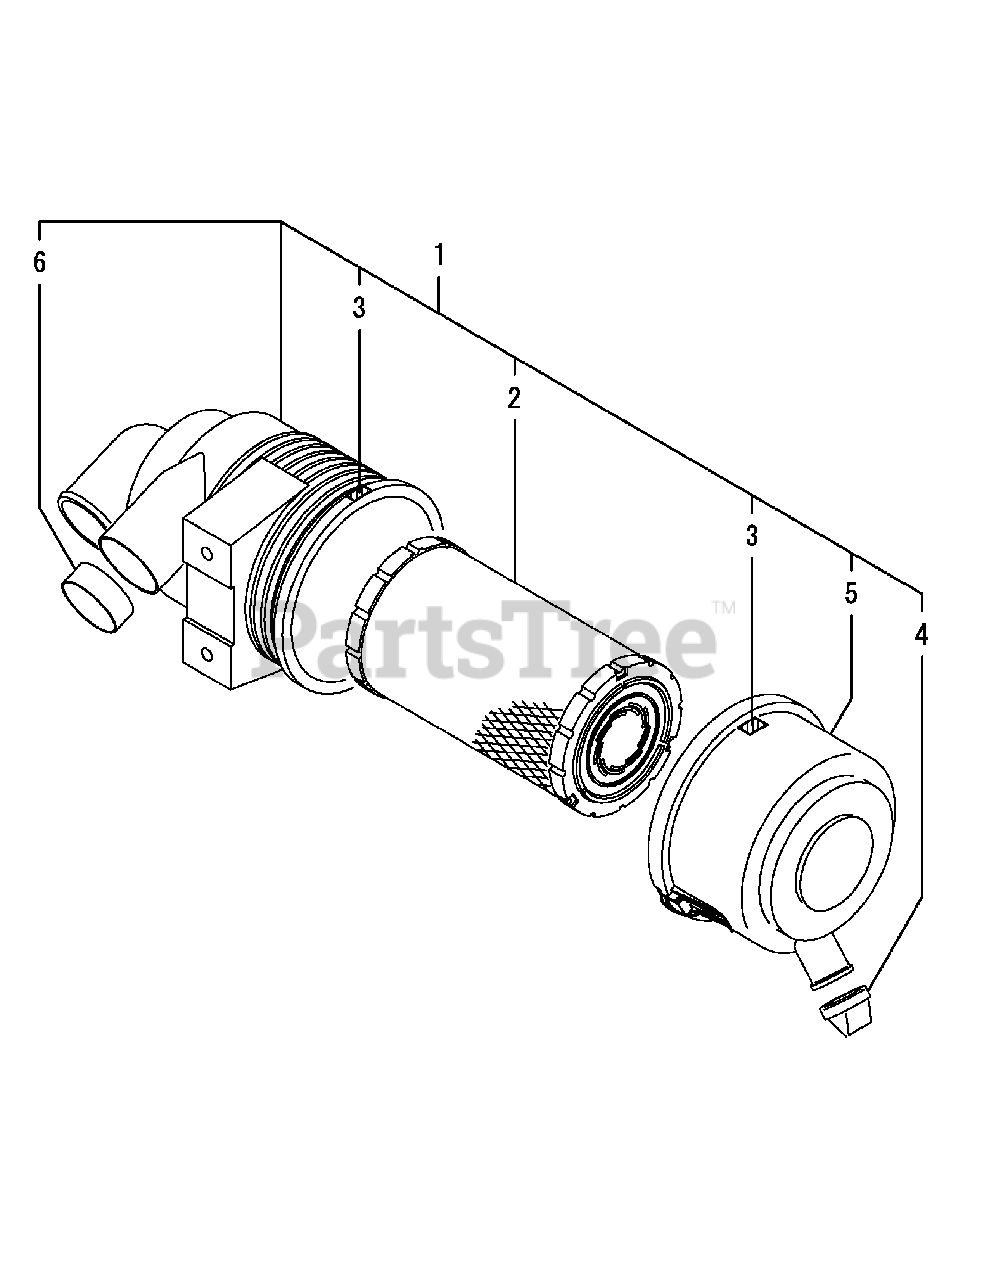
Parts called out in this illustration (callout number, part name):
1	CLEANER ASSY, AIR
2	ELEMENT 4,CLEANER
4	VALVE, UNLOADER
